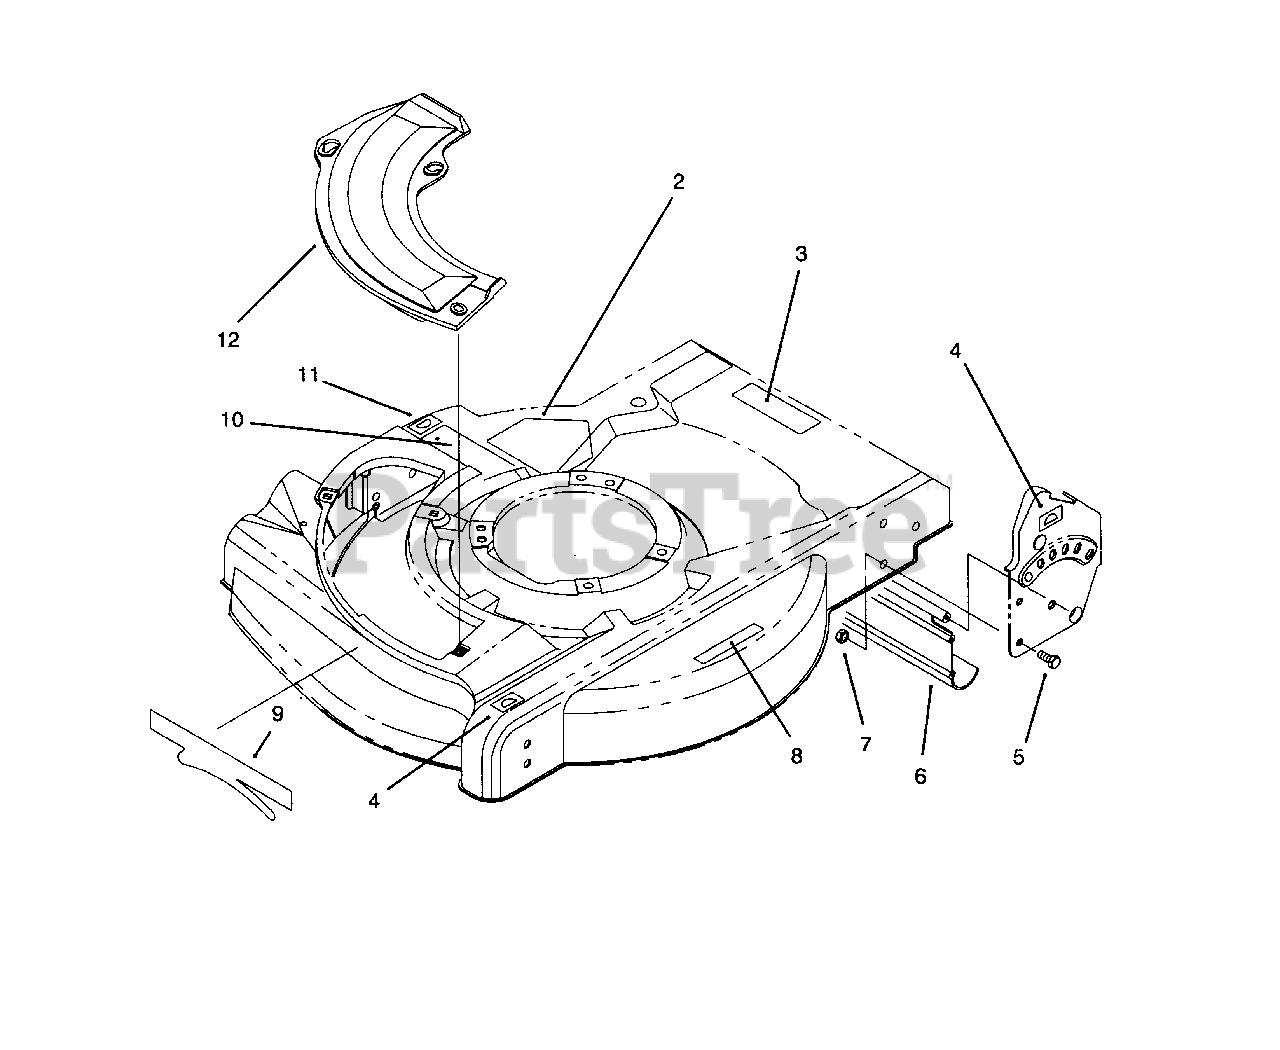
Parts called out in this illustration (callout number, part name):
2	Decal-Danger
3	Decal-Warning
4	Decal-H.O.C.
5	Screw-Hex Hd. Cap
6	Shield-Trailing
7	Nut-Lock
8	Decal-Danger
9	Decal-Deck
10	Decal-Discharge
11	Decal-H.O.C.
12	Plate-Cover
